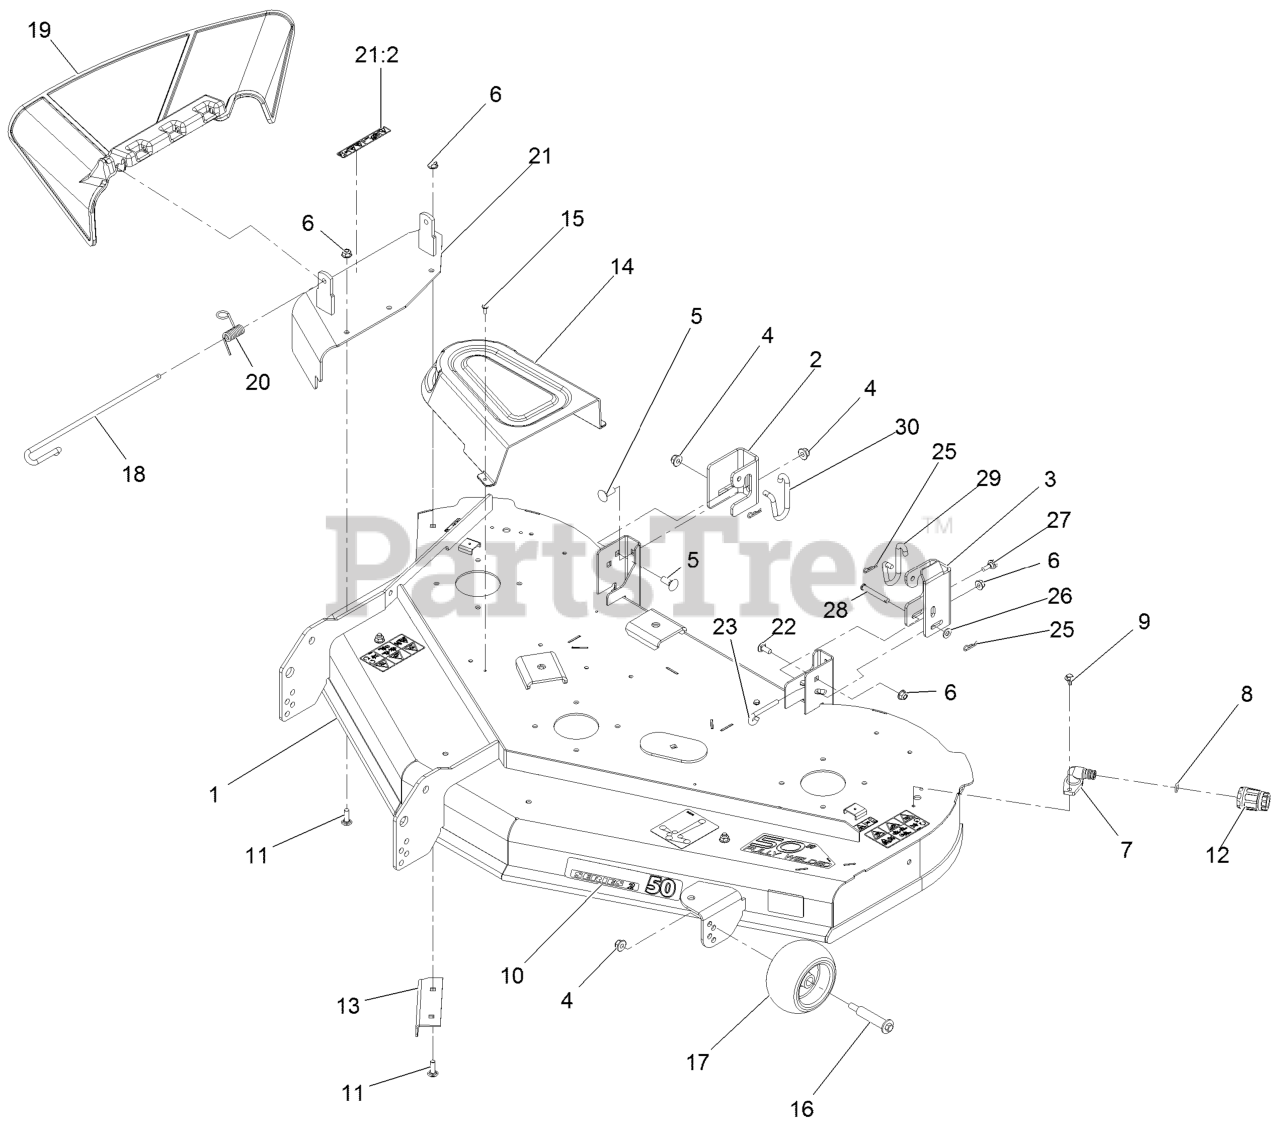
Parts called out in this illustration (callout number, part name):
1	DECK AND DECAL ASM
2	BRACKET-HANGER, RH
3	BRACKET-HANGER, LH
4	NUT-HF, NI
5	BOLT-CARR
6	NUT-HF, NI
9	SCREW-HHFTF
10	DECAL-SERIES 2 - 50
11	SCREW-CARR
12	CONNECTOR-HOSE
13	BAFFLE-CUTOFF
14	COVER-BELT
15	SCREW-TAPTITE
16	BOLT-SHOULDER
17	ROLLER-SCALP, ANTI
18	PIN-CHUTE
19	DEFLECTOR-DISCHARGE
20	SPRING-TORSION
21	COVER ASM W/DECAL
21:2	DECAL-DANGER
22	SCREW-CARR
23	ROD-LEVEL, DECK
25	PIN-COTTER
26	WASHER-PLAIN
27	SCREW-SHOULDER,HWH
28	PIN-CLEVIS
29	LINK-RETENTION, DECK (RH)
30	LINK-RETENTION, DECK (LH)
